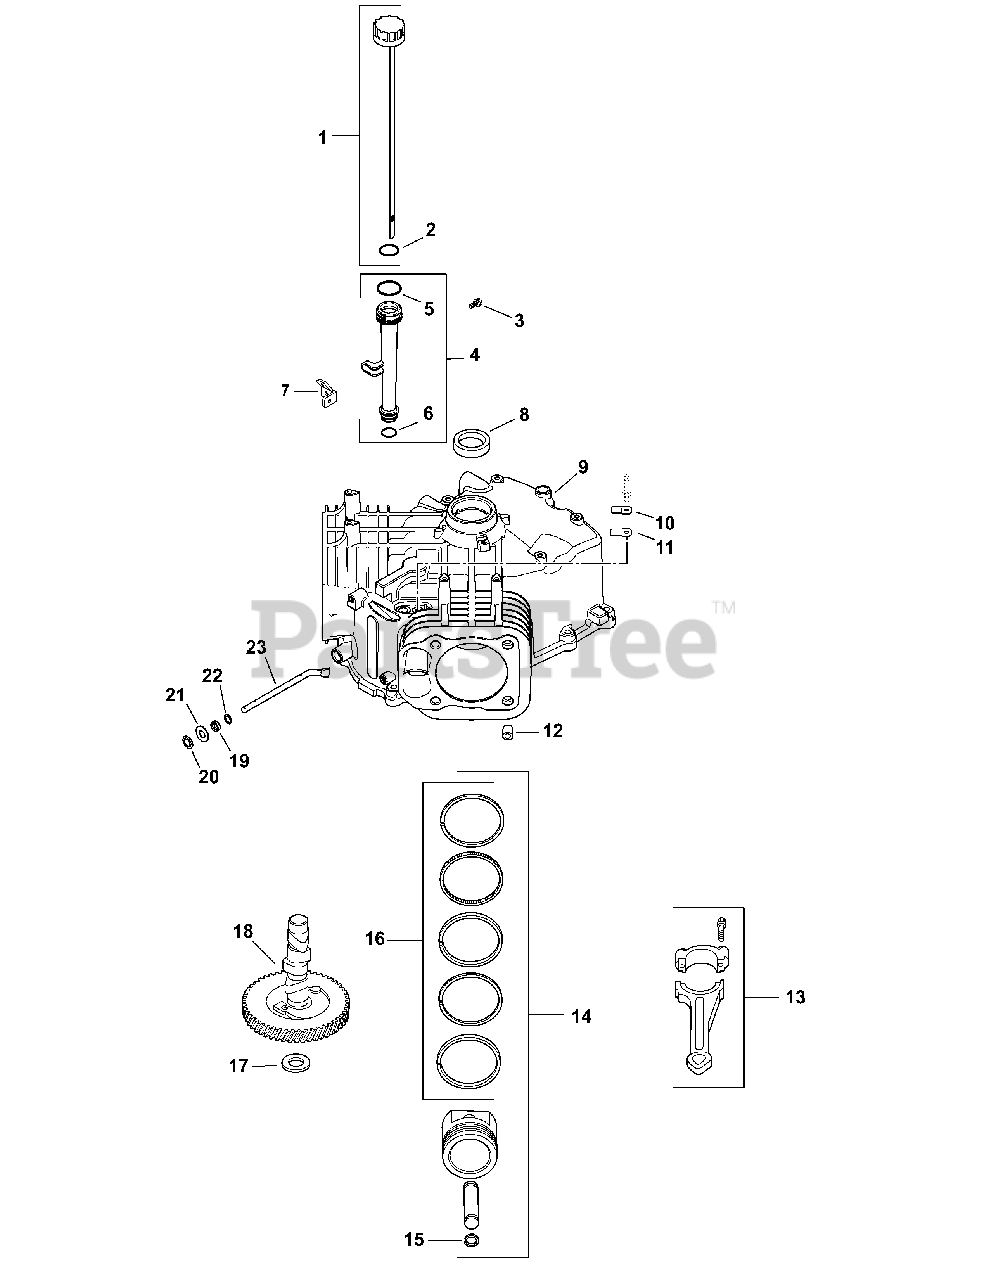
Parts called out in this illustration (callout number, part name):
1	Dipstick, Assy (Cub Yellow) (includes 2)
2	O-Ring, Dipstick
3	Screw, Flg Thd Frm M5x0.8x13
4	Kit, Oil Fill Cap (Includes 5, 6)
5	O-Ring, Upper Oil Fill Tube
6	O-Ring, Lower Oil Fill Tube
7	Bracket, Oil Fill Tube
9	Crankcase (use: Shortblock )
9	Shortblock
10	Retainer, Breather Reed
11	Reed, Breather
12	Pin, Locating
13	Connecting Rod (STD)
14	Kit, Piston w/ Ring (STD) (Includes 15, 16)
14	Kit, Piston w/ Ring (.25)
14	Kit, Piston w/ Ring (.08)
15	Retainer, Piston Pin
16	Ring Set (STD & .08)
16	Ring Set (.25)
17	Shim, Camshaft (White .028)
17	Shim, Camshaft (Blue .03)
17	Shim, Camshaft (Red .032)
17	Shim, Camshaft (Yellow .034)
17	Shim, Camshaft (Green .036)
17	Shim, Camshaft (Gray .038)
17	Shim, Camshaft (Black .04)
18	Kit, Camshaft (Includes Lubricant)
19	Seal, Governor Cross Shaft
20	Retainer Ring
21	Washer, Flat 9MM
22	Washer, Flat 11/32"
23	Shaft, Governor Cross
